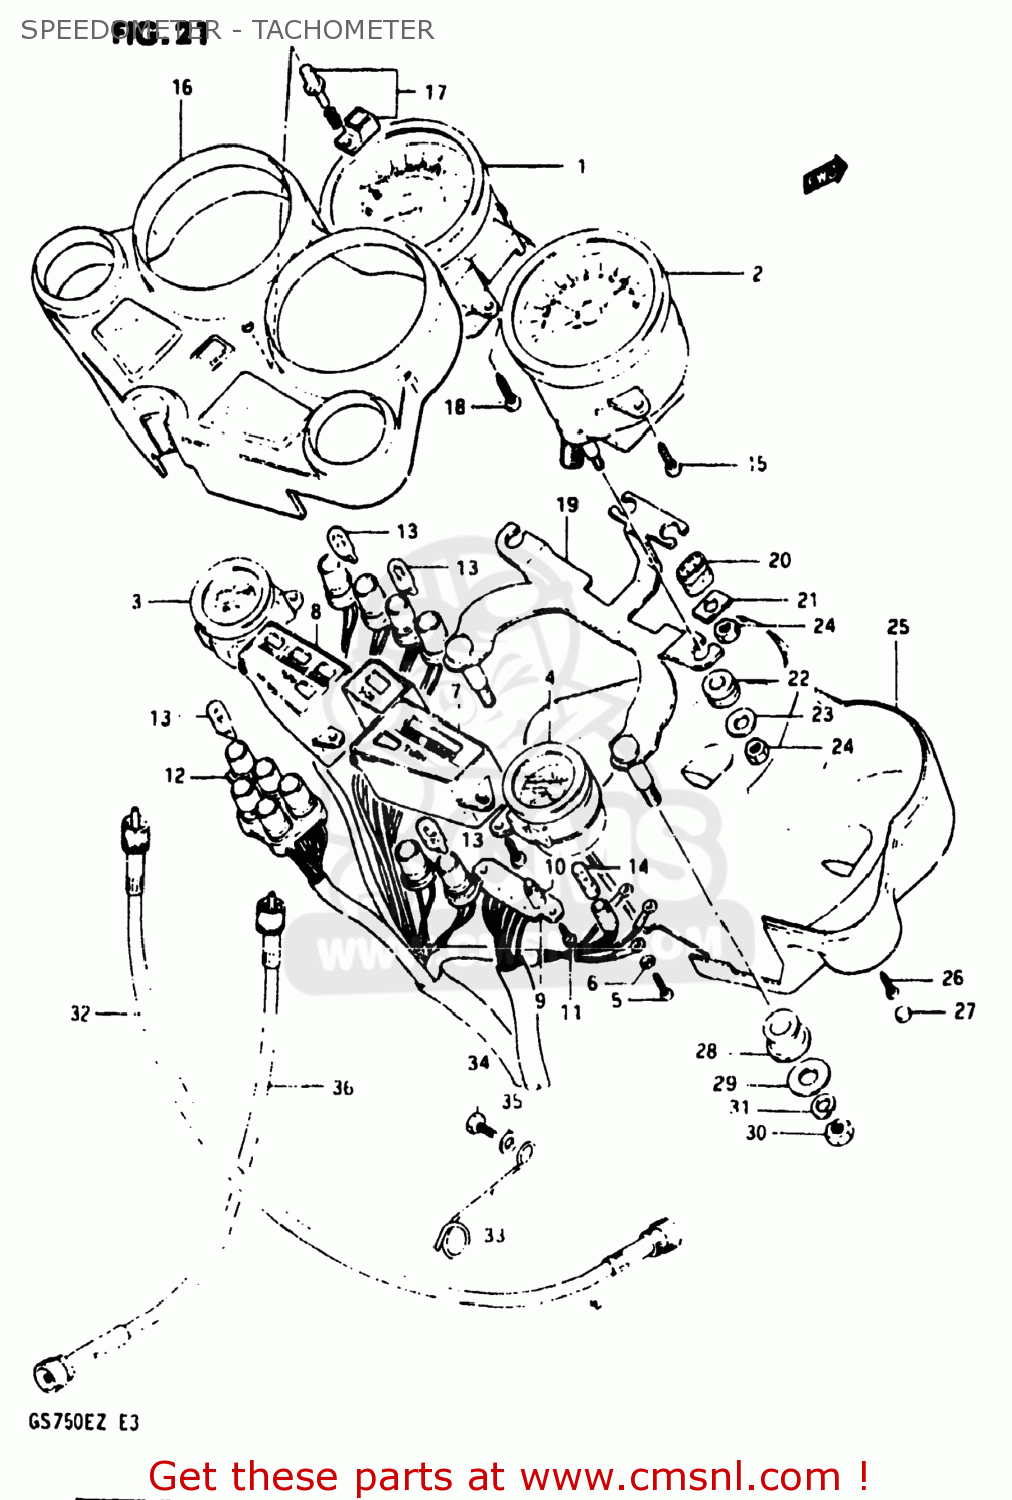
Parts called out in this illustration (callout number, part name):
0	SCREW
1	SPEEDOMETER ASSEMBLY
2	TACHOMETER
3	METER,FUEL
4	METER,OIL TEMPERATURE
5	SCREW
6	WASHER
7	CASE ASSEMBLY,PILOT LAMP
8	CASE ASSEMBLY,PILOT LAMP
9	SOCKET,GEAR INDICATOR
10	BULB(14V1.12W)
11	SCREW,GEAR INDICATOR
12	SOCKET,SPEEDOMETER
13	BULB(12V3.4W,T10)
16	HOOD,METER
17	KNOB,TRIP METER
18	SCREW
19	BRACKET,COMBINATION METER
20	CUSHION,METER
21	WASHER,METER
22	CUSHION,METER
23	WASHER,METER
24	NUT
25	COVER,METER,UNDER
26	SCREW
27	CAP,METER LOWER CASE
28	CUSHION,METER BRACKET
29	WASHER (8.5X29X1.6)
30	NUT
31	LOCK WASHER
32	CABLE ASSEMBLY,SPEEDOMETER
33	CLAMP,SPEEDOMETER CABLE
34	BOLT, UPPER
35	WASHER
36	CABLE ASSEMBLY,TACHOMETER
